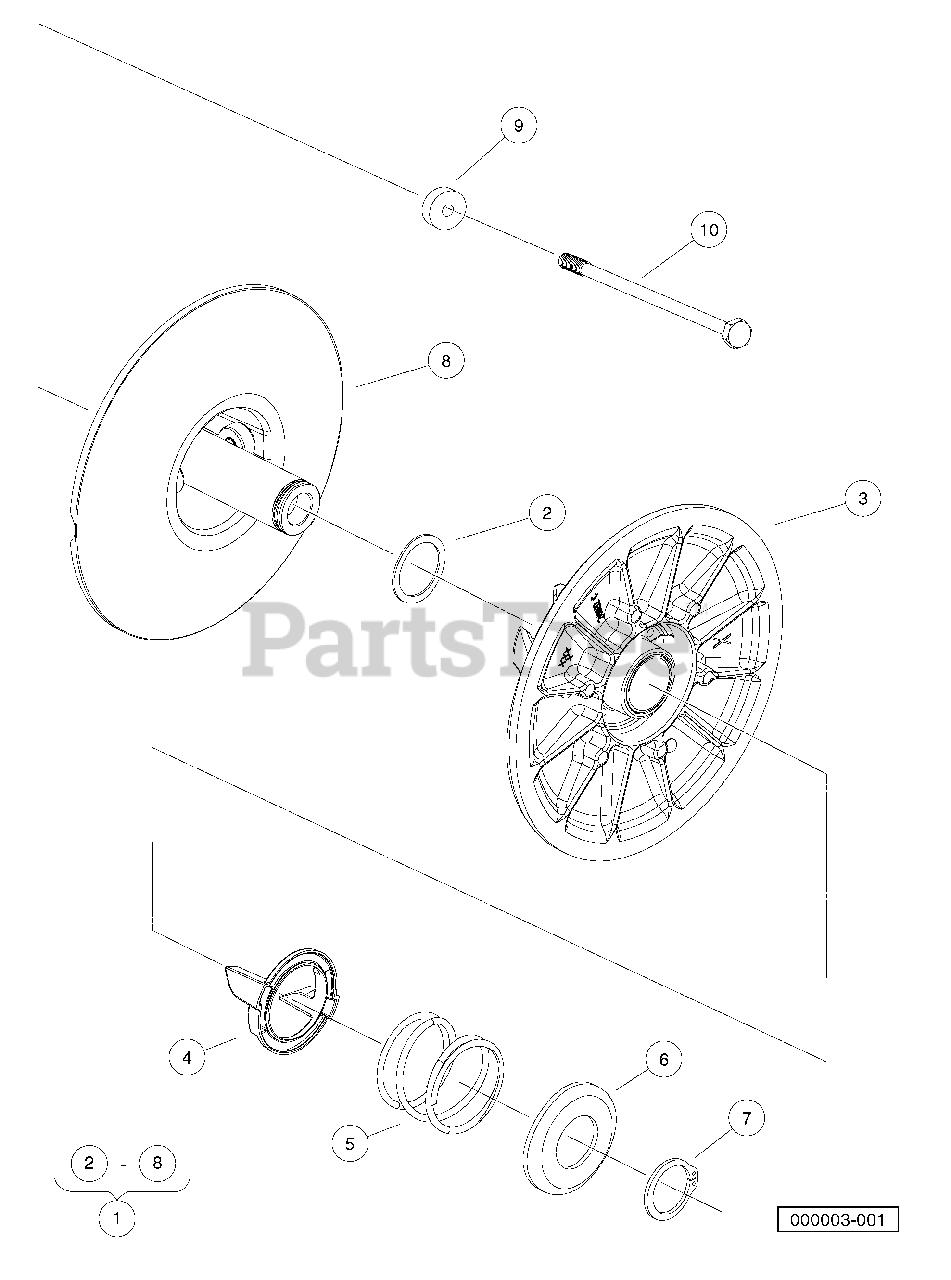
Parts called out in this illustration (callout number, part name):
1	CVT, Secondary
2	Washer, Thrust, 1.53 X 1.92
3	Sheave, Driven Clutch
4	Retainer, Spring, Inner
5	Spring, Compression, Secondary
6	Retainer, Spring, Outer
7	Ring, Retaining, External
8	Driven Clutch Base Sheave
9	Washer, Stepped
10	Bolt, M10 X 1.5 X 100 Loctite
